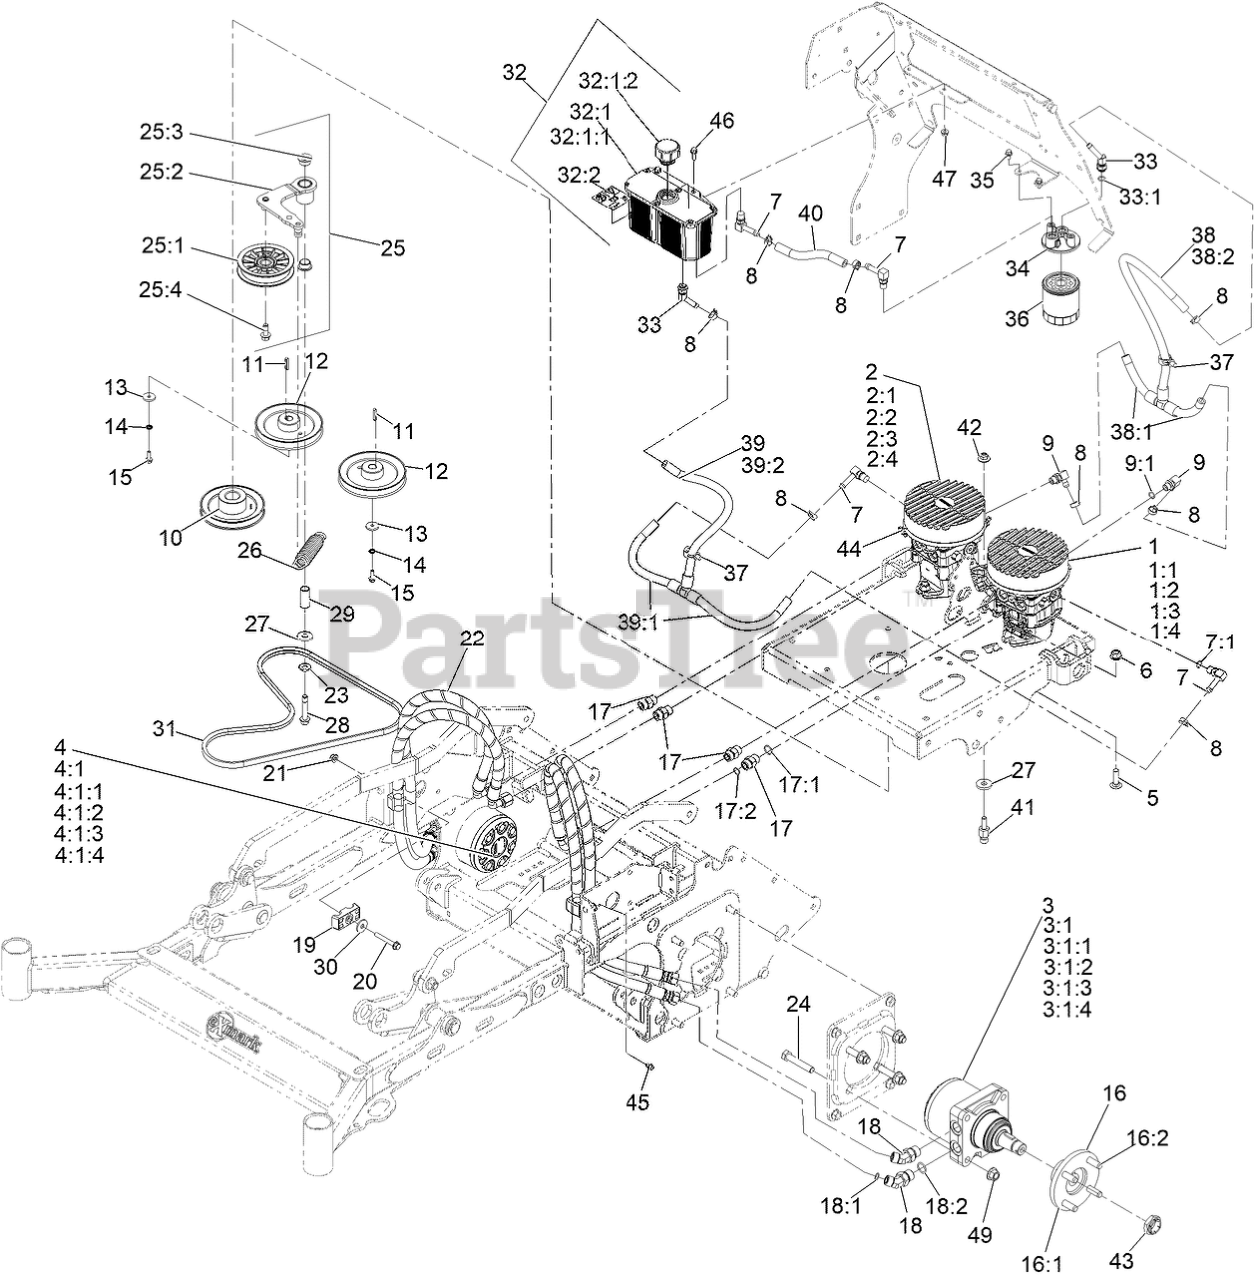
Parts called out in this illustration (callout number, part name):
1	PUMP-12CC LT W/SHOCK VALVE
1:1	KIT, 10CC/12CC PUMP KIT
1:2	SEAL OVERHAUL KIT
1:3	GUARD-PUMP
1:4	PUMP-COOLING
2	PUMP-12CC RT W/SHOCK VALVE
2:1	KIT, 10CC/12CC PUMP KIT
2:2	SEAL OVERHAUL KIT
2:3	GUARD-PUMP
2:4	PUMP-COOLING
3	MOTOR, TL240 LH
3:1	SEAL KIT
4	MOTOR, TL240 RH
4:1	SEAL KIT
4:1:1	Seal-Ring, Viton
4:1:2	Seal-Commutator
4:1:3	Seal-Dirt/Water, Hi Temp
4:1:4	Seal-Shaft
5	BOLT-CARR
6	NUT-HF, NI
7	FITTING-ELBOW, 90
7:1	O-RING
8	CLAMP-HOSE
9	FITTING-90 DEG
9:1	O-RING
10	SHEAVE-PUMP, DRIVE
11	KEY, 5MM X 5MM X 29MM
12	SHEAVE-PUMP
13	WASHER-1.00 OD X .25 ID
14	WASHER-SPRING
15	SCREW-HHF
16	WHEEL HUB / STUD ASM
16:1	HUB-WHEEL
16:2	STUD-TYPE, DRIVE
17	FITTING-STRAIGHT
17:1	O-RING
17:2	O-RING
18	Fitting-HYD, 45 DEG
18:1	O-RING
18:2	O-RING
19	CLAMP-TUBE
20	CLAMP-TUBE
21	NUT-HF, NI
22	HOSE ASM-HYD HP
23	WASHER-BELLEVILLE
24	SCREW-HH
25	ASM-PUMP IDLER
25:1	PULLEY-IDLER, FLAT
25:2	ASM-PUMP IDLER ARM
25:3	BUSHING-FLANGE
25:4	SCREW-HFH
26	SPRING, EXTENSION
28	SCREW-HHF
29	PIVOT, IDLER
31	BELT- COG A 54
32:1	Reservoir-HYD
32:1:1	Cap-Reservoir, HYD
32:1:2	GASKET-CAP
32:2	DECAL-WARNING
33	FITTING-BARBED, 45 DEG
33:1	O-RING
34	HEAD-FILTER
35	SCREW-HHF
36	FILTER-25 MICRON, BI-DIRECTIONAL
37	CLIP-TIE
38	ASM-HYDRAULIC LO-PRES
38:1	HOSE, LP HYDRO
38:2	HOSE, LP HYDRO
39	ASM-HYDRAULIC LO-PRES
39:1	HOSE, LP HYDRO
39:2	HOSE, LP HYDRO
40	HOSE, LP HYDRO
41	PIN-SPRING, ANCHOR
42	Nut-Nyloc 3/8-16 Flg
43	LOCKNUT
44	TIE-CABLE
46	SCREW-HHF
47	NUT-HHF
49	Nut-Lock 1/2-13
